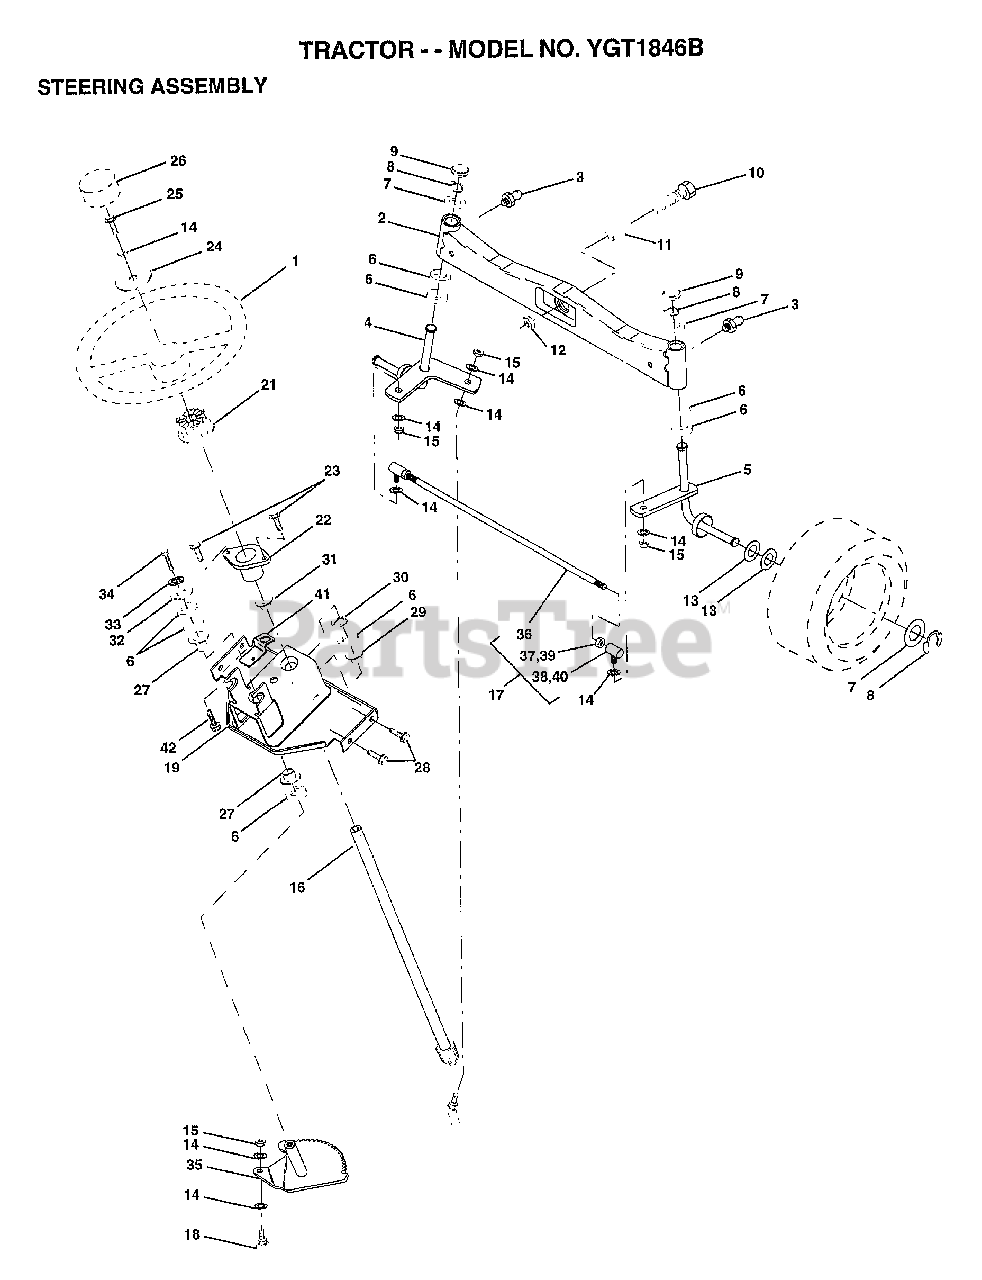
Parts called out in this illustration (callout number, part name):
3	ZERK M
4	SPINDLE ASM LH
5	SPINDLE ASM RH
6	WASHER .T
7	WASHER
8	RING
9	CAP
10	BOLT
11	SPACER BEARING
12	"NUT-LOC,FLANGE LT"
13	WASHER
14	LOCKWASHER
15	GRIPCO NUT
16	SHAFT.STEER.VGT
17	ROD.ASM.TIE.BALL
18	DRAGLINK.BALL.JOI
19	SUPPORT ASM-STEER
21	ADAPTER LT
22	"BUSHING,STEERING"
23	"SCREW-TT,10-32 FL"
24	WASHER T
25	BOLT
26	"INSERT,STR WHEEL"
27	COL. SRTG. BEAR.
28	SCREW
29	"FLANGE GT, BEAR."
30	KLIP RING
31	BUSHING.NYLINER.
32	WASHER
33	LOCKWASHER
34	BOLT
35	GEAR.ASM.SECTOR.
37	NUT
38	JOINT.RH
39	NUT
40	JOINT.LH
41	"BRKT-SW, INTER"
42	SCREW LT
